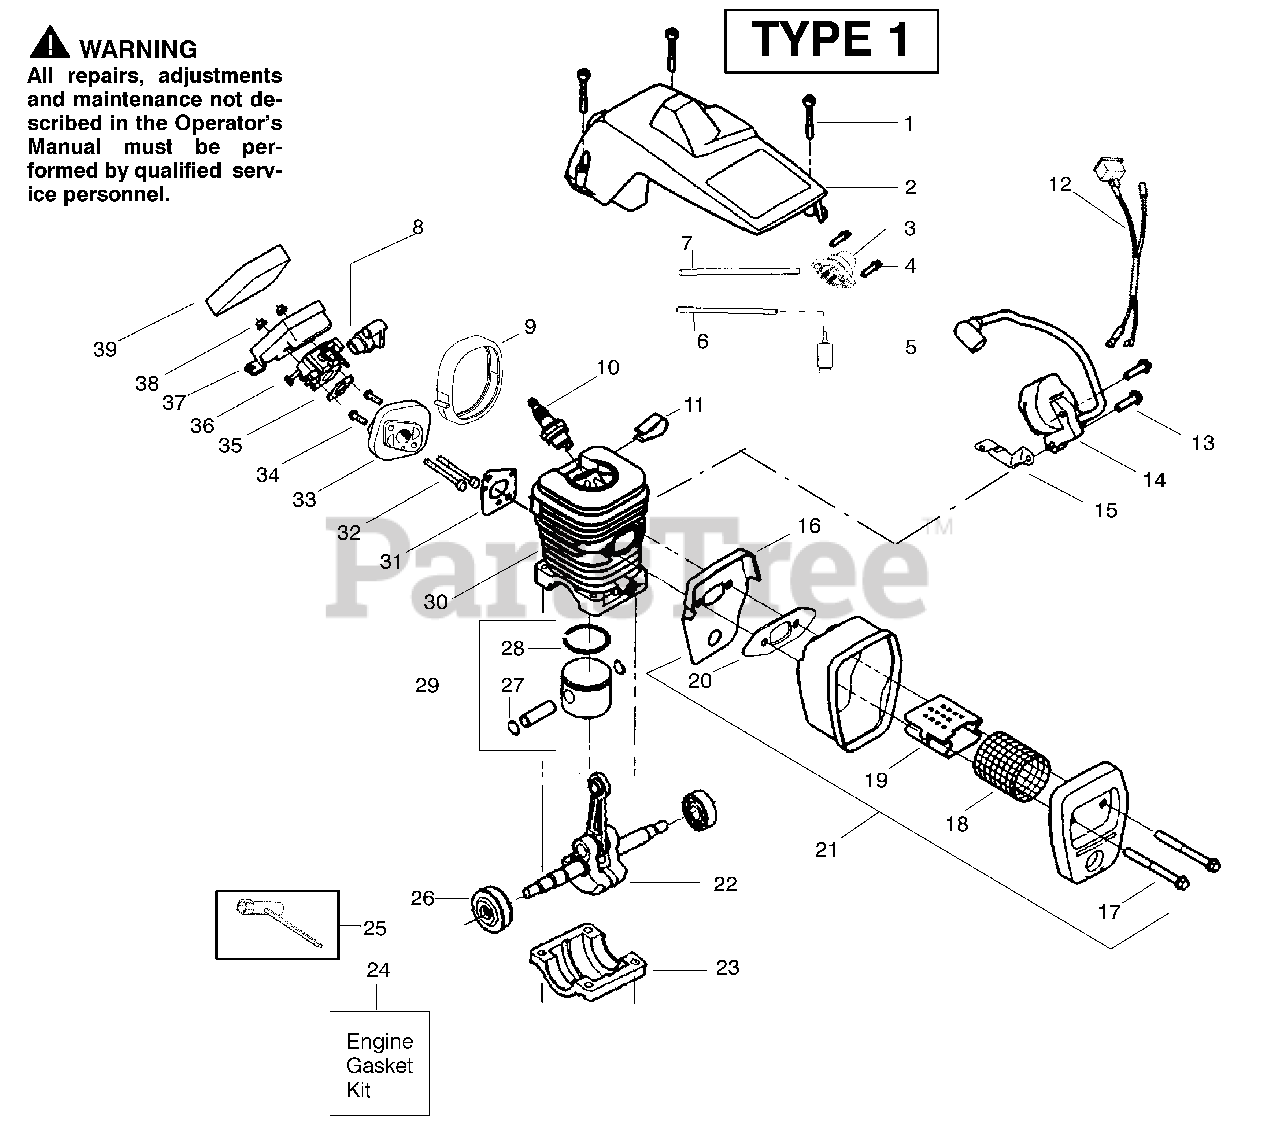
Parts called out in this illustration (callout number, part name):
2	Shield-Cylinder
3	Assy-Air Purge
5	Assy-Fuel Pick-Up
6	Kit-Line Purge/Carb.
7	Kit-Line Purge/Tank
8	Grommet-Carb Adjust.
9	Seal-Carb Adapter
10	Spark Plug
11	Clip-High Tension Lead
12	Assy-Wire Harness
14	Module-Ignition
15	Strap-Ground
16	Back Plate-Muffler
18	Screen-Spark
19	Diffuser-Muffler
20	Gasket-Muffler
21	Assy-Muffler
22	Assy-Crankshaft
23	Cap-Crankcase
24	Kit-Engine Gasket
26	Assy-Seal & Bearing
27	Retainer - Piston Pin
28	Ring-Piston
29	Kit-Piston
30	Cylinder
31	Gasket-Adapter
33	Adapter-Carb.
35	Carb. Gasket
36	Kit-Carburetor
37	Housing-Air Filter
39	Air Filter - Foam
